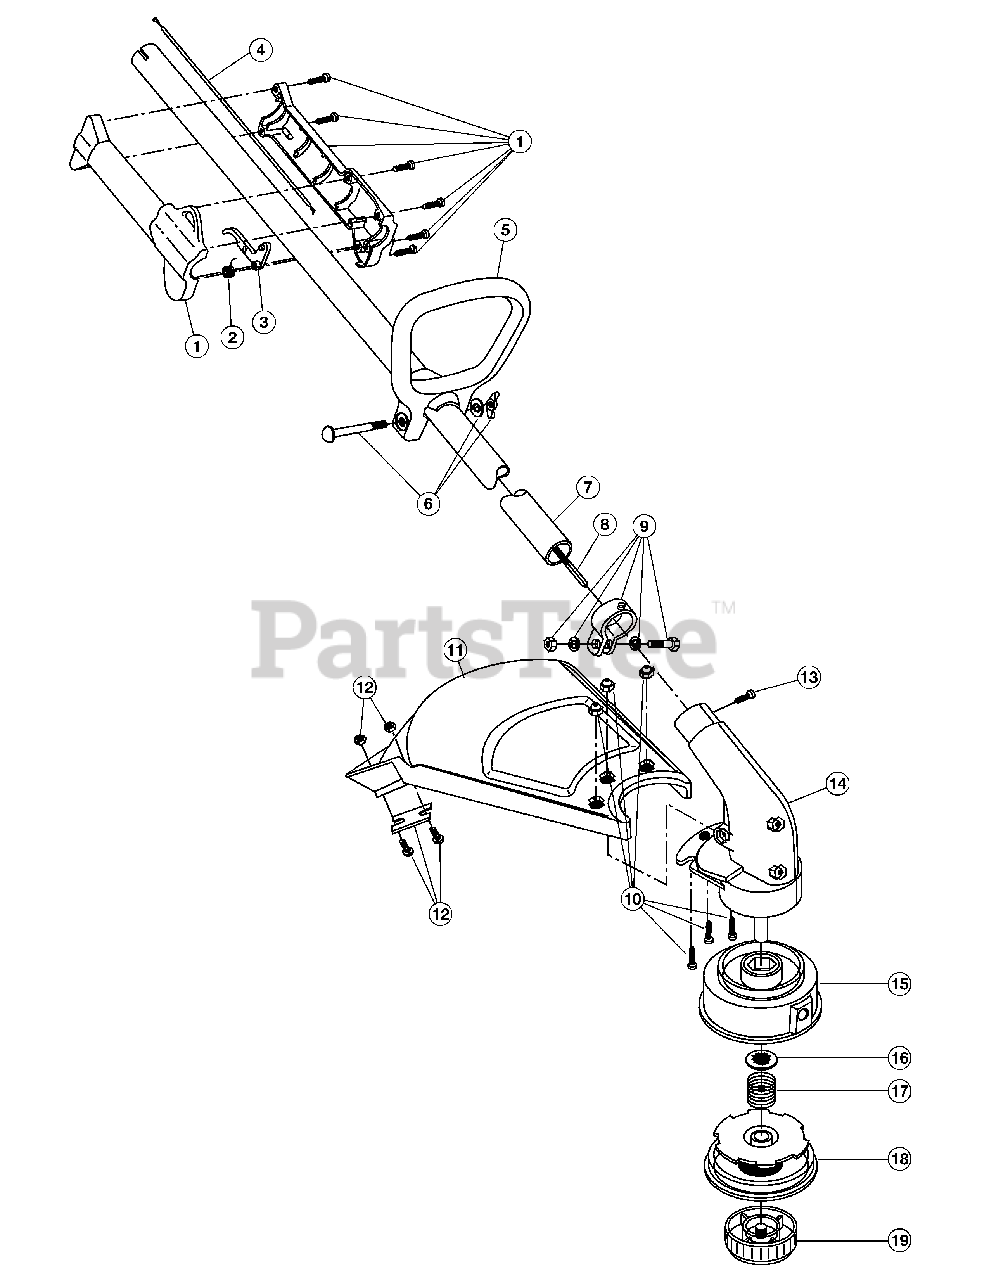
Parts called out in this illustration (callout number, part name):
1	Throttle Housing Assembly (includes 2-3)
2	Throttle Trigger Spring
3	Throttle Trigger
4	Throttle Cable
5	D-Handle
6	D-Handle Hardware Assembly
7	Drive Shaft Housing Assembly
8	Flexible Drive Shaft
9	Lower Clamp Assembly (includes 13)
10	Guard Mounting Screw Assembly
11	Guard Assembly (includes 12)
12	Blade Assembly
13	Anti-Rotation Screw
14	Gearbox Assembly (includes 15 & 16)
15	Outer Spool and Eyelet Assembly
16	Retainer (10 pack)
18	Inner Reel
19	Bump Head Knob Assembly
